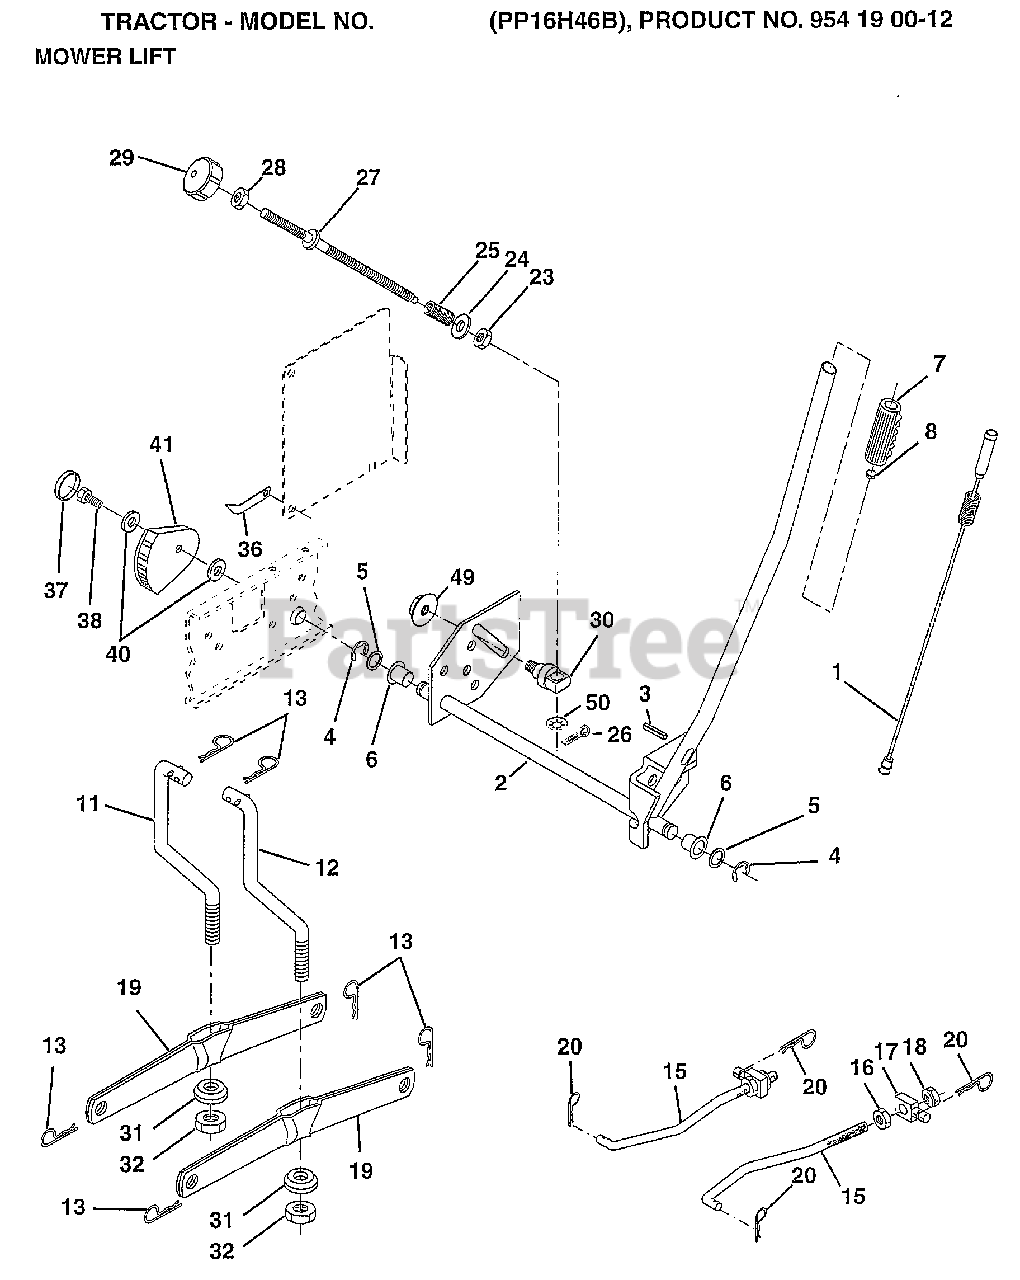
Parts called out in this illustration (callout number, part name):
1	WIRE ASM W.SPRING
2	"SHAFT ASM LIFT,RH"
3	PIN-GROOVE LT
5	WASHER
6	NYLON BEARING
7	GRIP
15	LINK.FRONT
16	NUT
17	TRUNION
18	NUT.LK.W/WSH.1/2.
19	ARM SUSP REAR
20	RETAINER.SPRING
23	NUT T
24	WASHER
25	SPRING T
28	NUT
29	KNOB INF 3/8-16
30	TRUNNION
31	BEARING PVT LH
32	NUT.CROWNLOCK.3/8
36	POINTER-INDICAT
37	"PLUG,HOLE"
38	SCREW
40	WASHER
41	INDICATOR HEIGHT
49	NUT.HXFLG.LOCK.
50	NUT PUSH M
